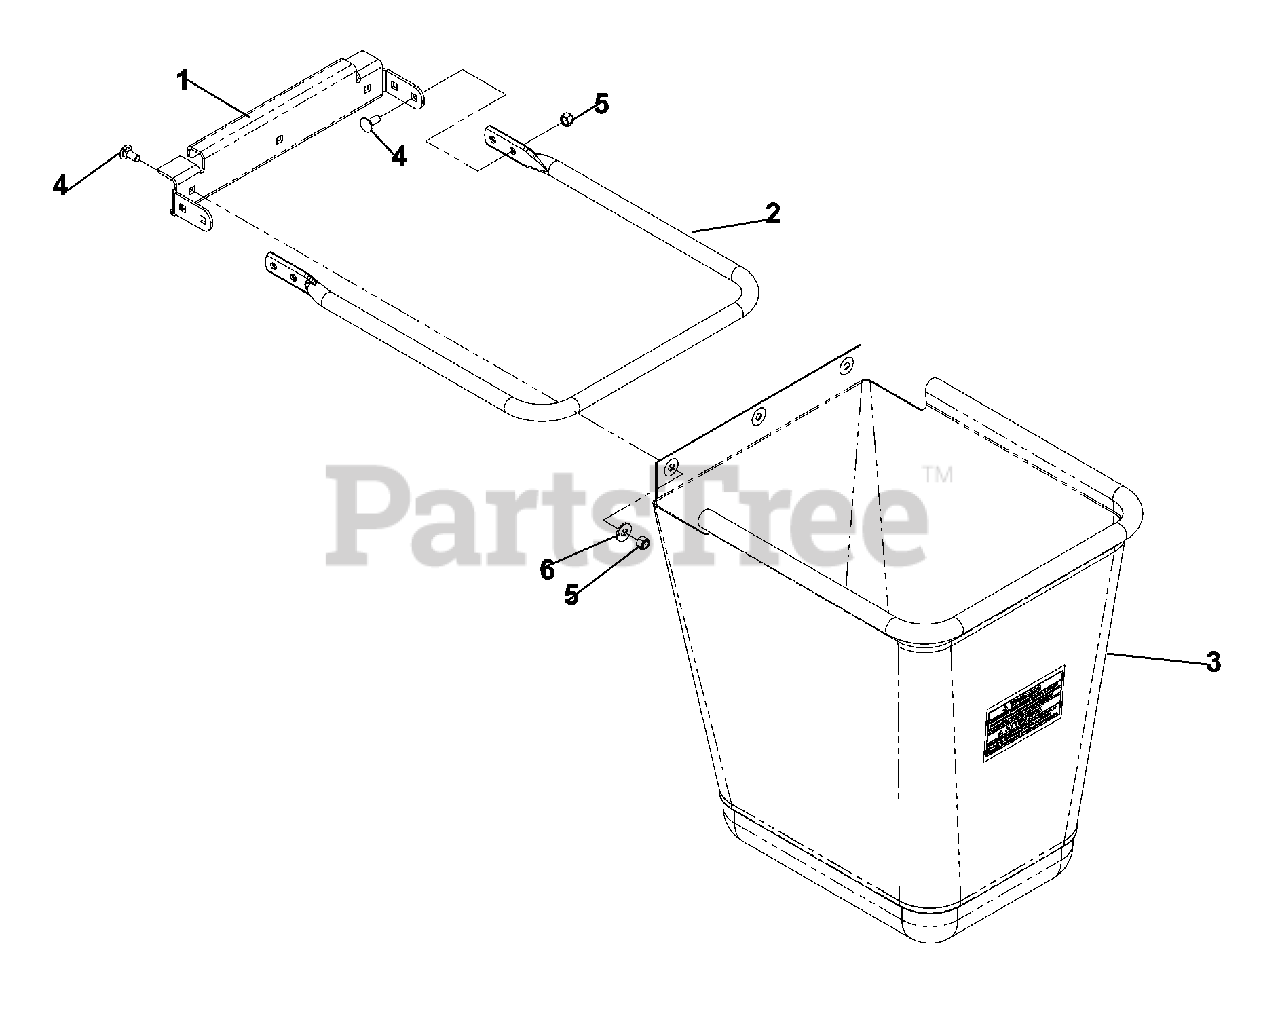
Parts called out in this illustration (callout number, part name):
1	HANGER, BAG
2	TUBE BAG FRAME
3	BAG, SMALL
4	BOLT 5/16C X 3/4" CARRIAGE
5	NUT 5/16 NYLOC
6	WASHER 5/16 FLAT
